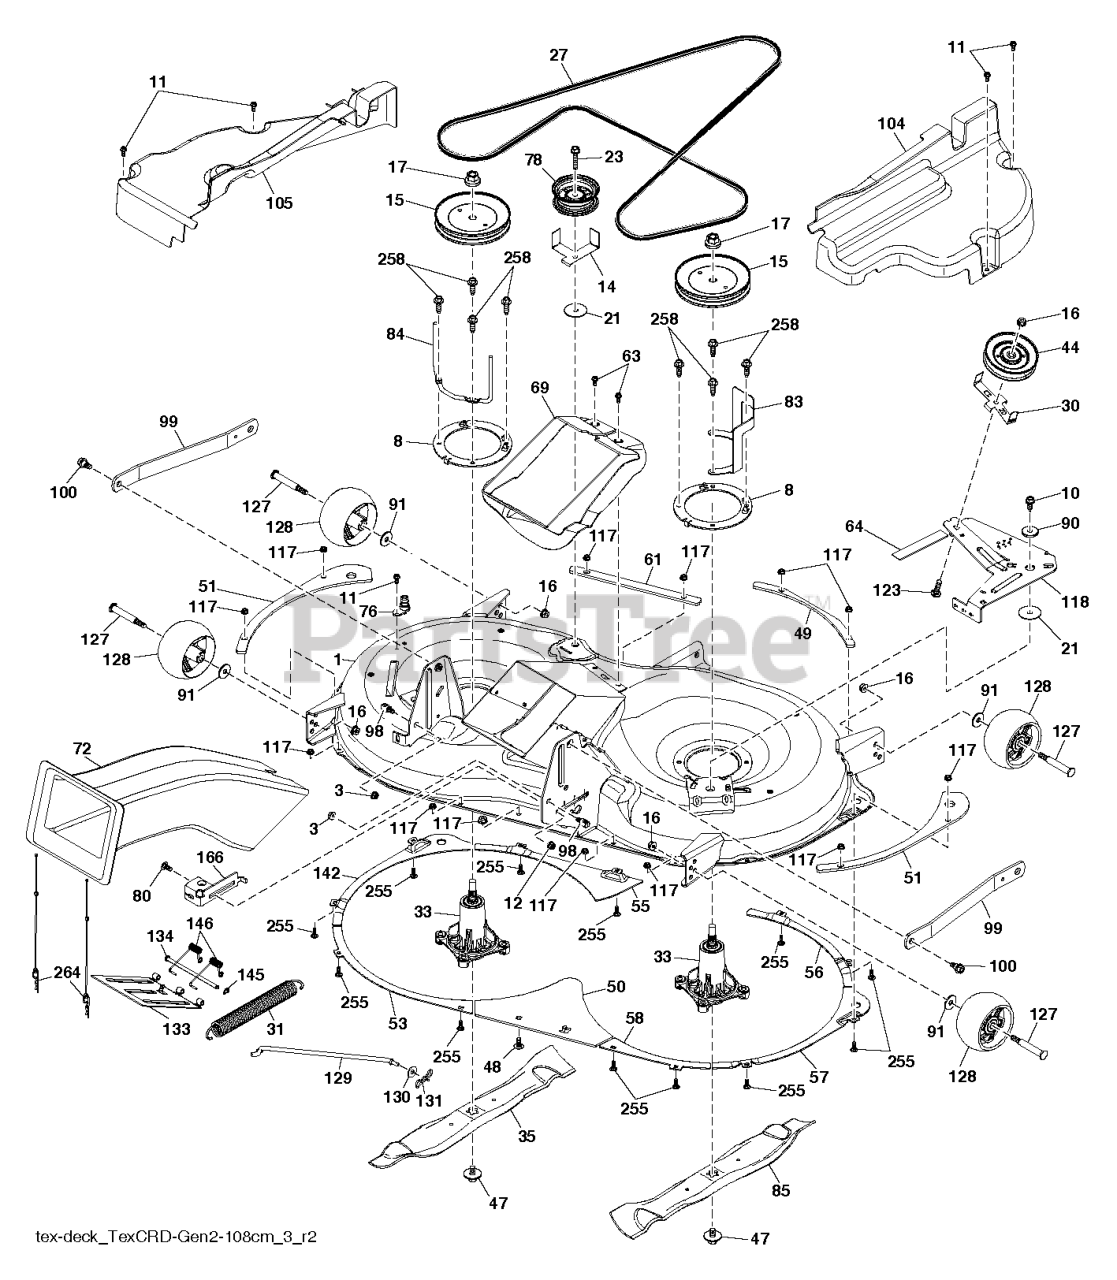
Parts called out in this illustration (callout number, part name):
3	GSPW Nuts
10	SCREW 3/8-16X1
11	SCREW.1/4-20X5/8
12	NUT HEXAGON FLANGE 5/16-18 ST
14	GUARD.TUV.IDLER.42
15	PULLEY.MANDREL.5.438.P
16	NUT LOCK FLG 3/8-16 UNC
21	WASHER, WEAR LT (1 2)
23	BOLT;HEX_3/8-16 X 1.78.CLRZINC
31	SPRING.EXTENSION
44	PULLEY.V.IDLER
47	SCREW.SEMS.7/16-20X1.HEX.HEAD
63	HEX.WASHER.HEAD 1/4-20 X .65
64	VIBRATION PAD
72	Chutes
76	PORT.WASHOUT
78	PULLEY.IDLER.48"PRIMARY
80	GSPW Bolts
84	KEEPER.BLT.PNT.MNDRL.PULL.6.25
90	SPACER.RETAINER
98	STUD.W/"D"ANTI-ROTATION
100	BOLT.SHOULDER
117	NUT T
123	GSPW Bolts
128	WHEEL.GAUGE.RALLY
129	ROD ROD. SWAY CRD GEN II
131	PIN.COTTER.5/16.BOW TI
145	E-RING.5/16"
146	SPRING SPRING: EZ MULCH DOOR
255	BOLT CUP HEAD SQUARE NECK BOLT
258	BOLT.HEX.WASHR.HED.313-18X1.19
